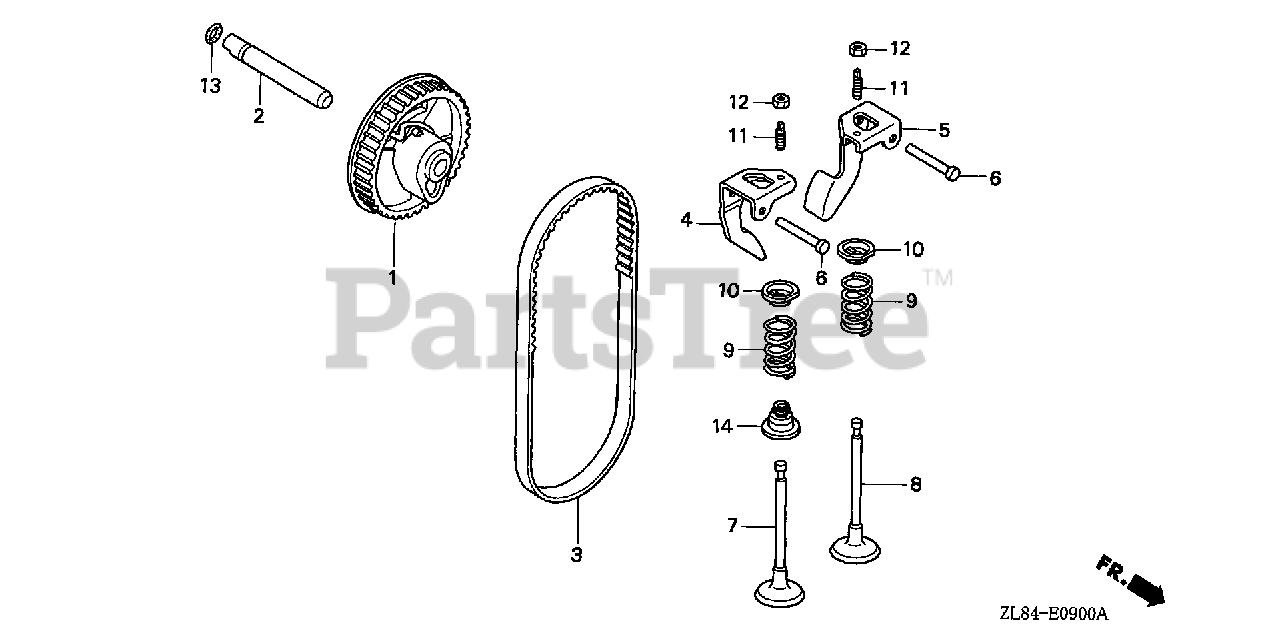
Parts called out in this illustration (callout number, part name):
1	PULLEY, CAMSHAFT
2	SHAFT, CAM PULLEY
3	BELT, TIMING (84HU7 G-200)
4	ARM, IN. VALVE ROCKER
5	ARM, EX. VALVE ROCKER
6	SHAFT, ROCKER ARM
7	VALVE, IN.
8	VALVE, EX.
9	SPRING, VALVE
10	RETAINER, IN. VALVE SPRING
11	SCREW, TAPPET ADJ.
12	NUT, TAPPET ADJ.
13	O-RING (6.8X1.9)
